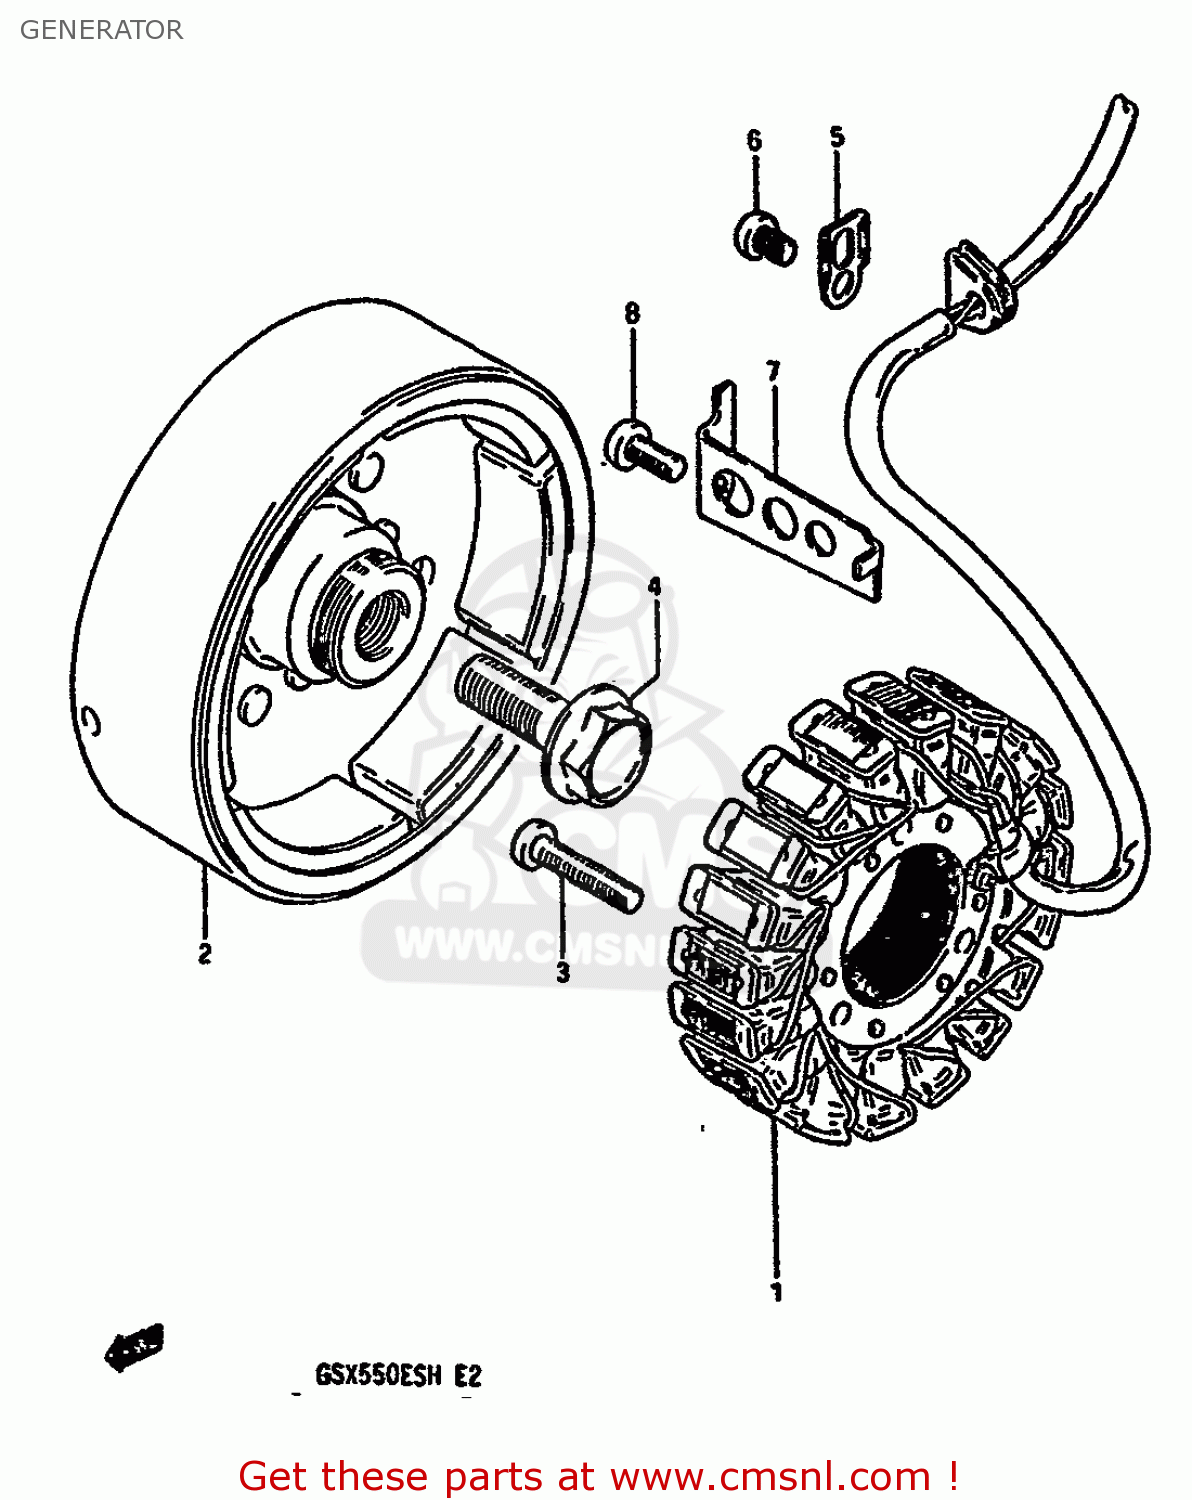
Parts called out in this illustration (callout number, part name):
1	STARTER ASSY
2	ROTOR ASSEMBLY
3	SCREW 6X30
4	BOLT(14X43)
5	CLAMP,GENERATOR LEAD WIRE
6	SCREW
7	CLAMP,GENERATOR LEAD WIRE
8	SCREW
